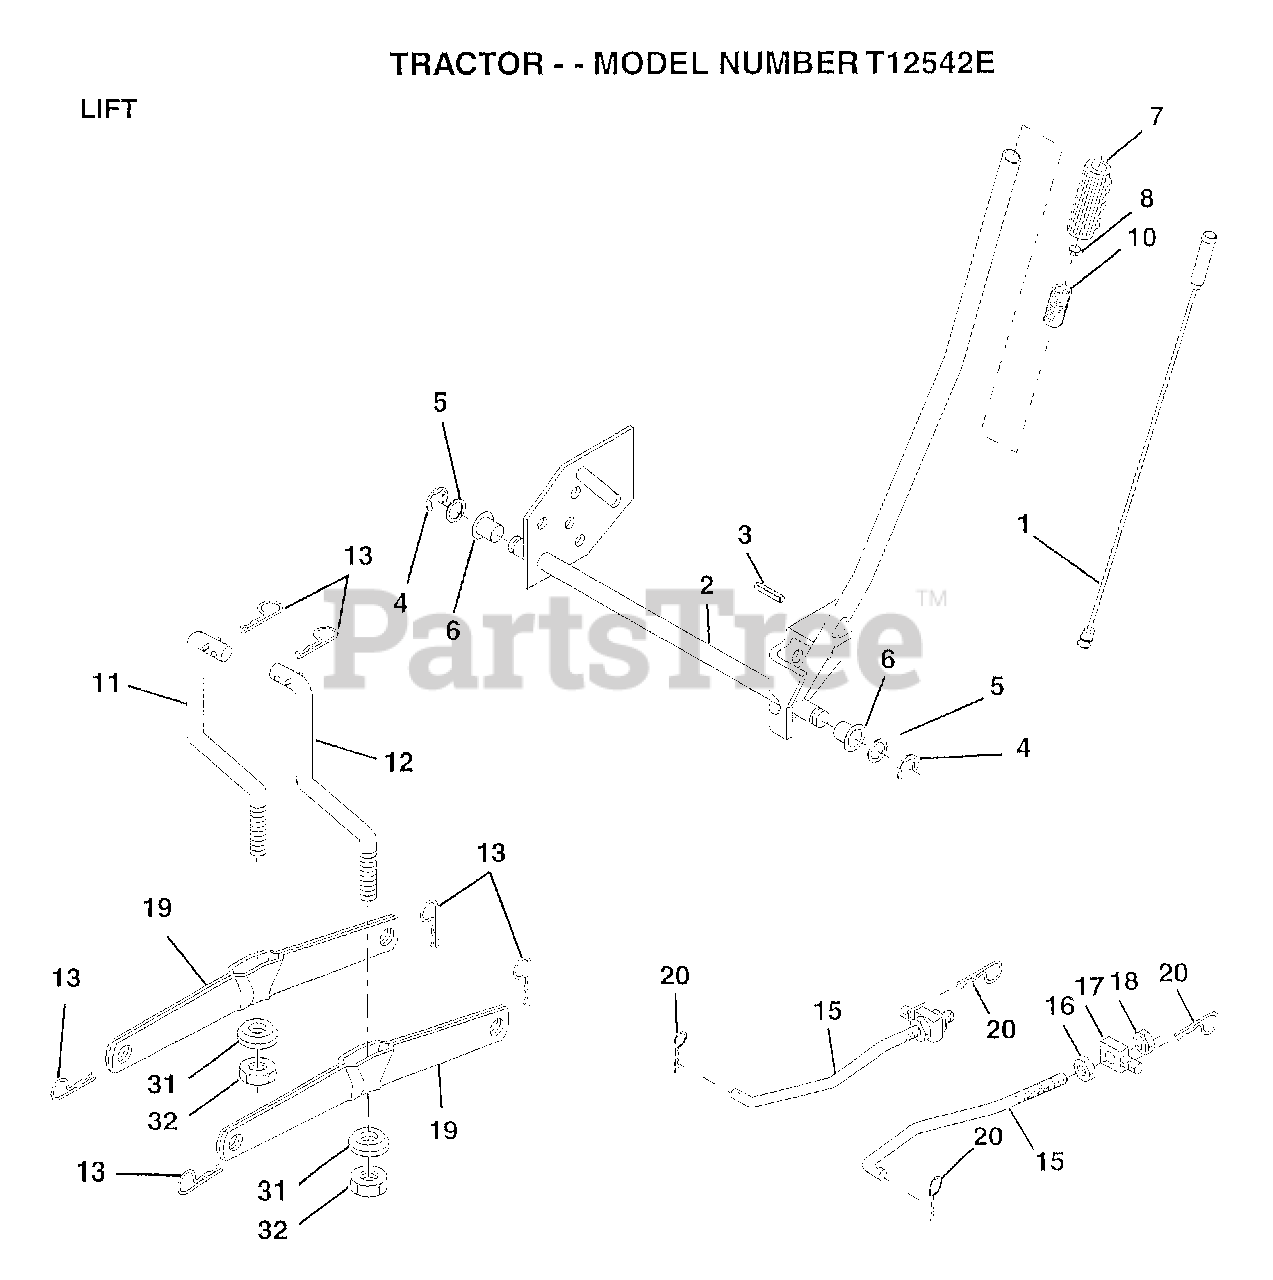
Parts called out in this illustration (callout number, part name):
1	WIRE ASM
2	SHAFT.LIFT.ASM.RH
3	PIN-GROOVE LT
5	WASHER
6	NYLON BEARING
7	GRIP
15	LINK.FRONT
16	NUT
17	TRUNION
18	NUT.LK.W/WSH.1/2.
19	ARM SUSP REAR
20	RETAINER.SPRING
31	BEARING PVT LH
32	NUT.CROWNLOCK.3/8
